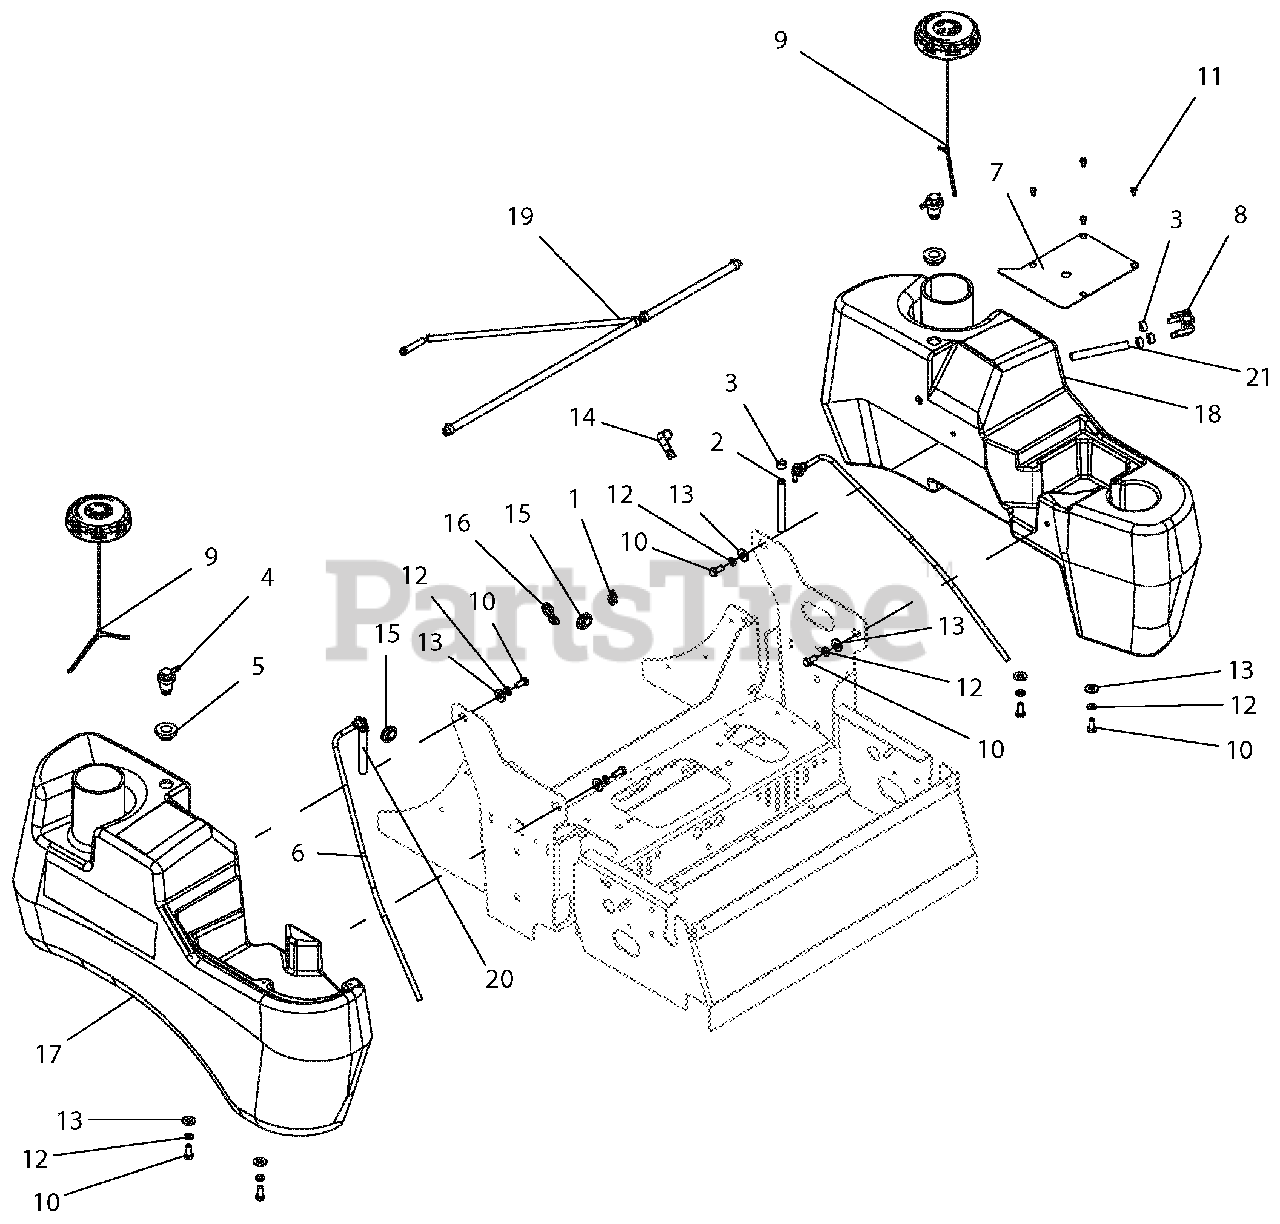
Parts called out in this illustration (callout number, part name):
1	CLIP, ROUTING (.50 ID)
2	.25 LOW-PERM GAS HOSE 19.00" LG - LH TANK TO VALVE
3	CLAMP, FUEL LINE
4	VALVE, COMBINATION
5	GROMMET, REMOTE VENT NITRILE
6	ASM, LARGE TANK FUEL PICKUP
7	PLATE, FUEL VALVE MOUNTING-RED
8	VALVE, FUEL
9	CAP, FUEL VENT-IN AUTOLOCK
10	BLT-HEX .31-18X.75 GR5 YWZC
11	SCR-MCH 10-24X.38 HWHSTAINLESS
12	WSHR-LK .31X.078 REG YWZC
13	WSHR-FL-STL.38X.875X.083 YWZC
15	GROMMET, RUBBER
16	CABLE TIE W/ TREE (.25 HOLE)
17	TANK, RH LARGE GRAVELY FUEL
18	TANK, LH LARGE GRAVELY FUEL
19	PT400, FUEL LINE ASSEMBLY
20	.25 LOW-PERM GAS HOSE 54.00" LG - RH TANK TO VALVE
21	.25 LOW-PERM GAS HOSE 28.00" LG - Valve to engine
